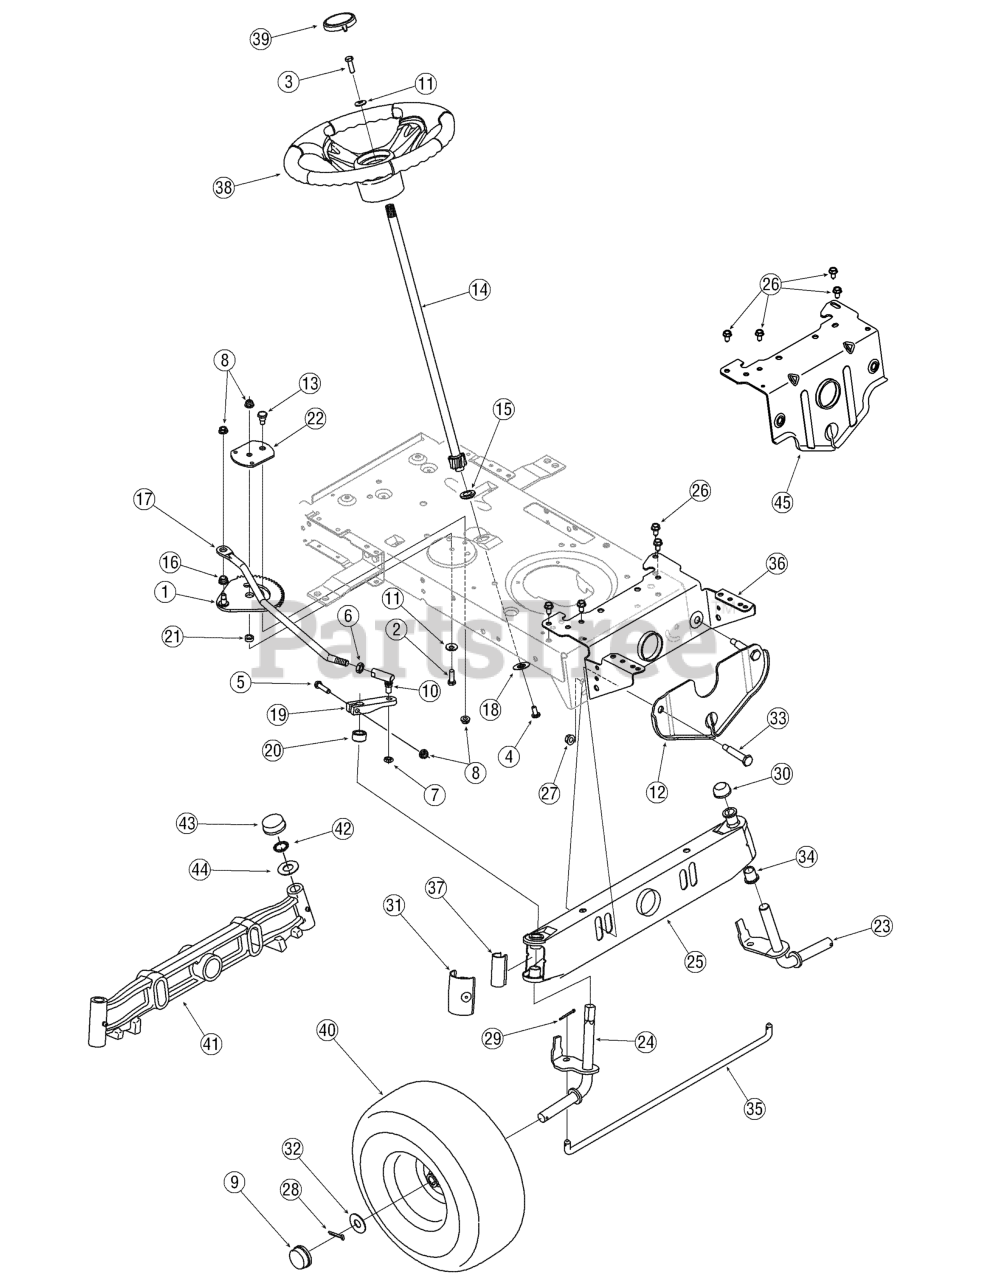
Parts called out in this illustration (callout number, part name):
1	Gear Assembly, Steering
2	Screw, 5/16-18, 1.00, Gr5
3	Screw, 5/16-18, 1.00, Gr5, Lock
4	Screw, Mach, 5/16-18, 0.750
5	Screw, 5/16-18, 1.75, Gr5
6	Nut, Jam, 7/16-20, Gr2
7	Nut, Jam Lock, 3/8-24, Gr2
8	Nut, Flange Lock, 5/16-18, Grf
9	Hub Cap
10	Ball Joint, 7/16-20, Lock
11	Washer, Bell, .340 x .872 x .060
13	Scr., Shlder, .435 x .3485, 5/16-18
14	Steering Shaft, 5/8 Spline x 21.86
15	Bearing, Flange, Hex 5/8
16	Plastic Bushing .380 ID
17	Drag Link, Steering
18	Cap, 1.25 x .16
20	Spacer, .710 ID x .125 OD x .56
21	Spacer, .322 ID x .625 OD x .21
22	Stabilizer Plate, Gear Segment
23	Axle Assembly, LH (38" & 42" Deck)
23	Axle Assembly, LH (46" Deck)
24	Axle Assembly, RH (38" & 42" Deck)
24	Axle Assembly, RH (46" Deck)
26	Screw, 5/16-18, 0.625
27	Nut, Flange Lock, 3/8-16, GrF
28	Pin, Cotter, 5/32, 1.25
29	Pin, Cotter, 1/8 x 0.75
30	Push Cap, 3/4
31	End Cap, Pivot Bar (Standard)
31	End Cap, Pivot Bar (w/ Fitting)
32	Washer, Flat, .781 x 1.59
33	Scr., Shlder, .500 x 2.380, 3/8-16
34	Bearing, Flange, .760 x .941 x 1.0
35	Tie Rod
37	Axle End Cap, Standard
38	Steering Wheel, Standard Grip
38	Steering Wheel, Soft Grip
39	Cap, Steering Wheel (no logo)
39	Cap, Steering Wheel (sprig logo)
39	Cap, Steering Wheel (tine logo)
41	Pivot Bar, Cast
42	Push Nut 3/4 Dia.
43	Push Cap
44	Washer, Flat, .78 x 1.59 x .60
